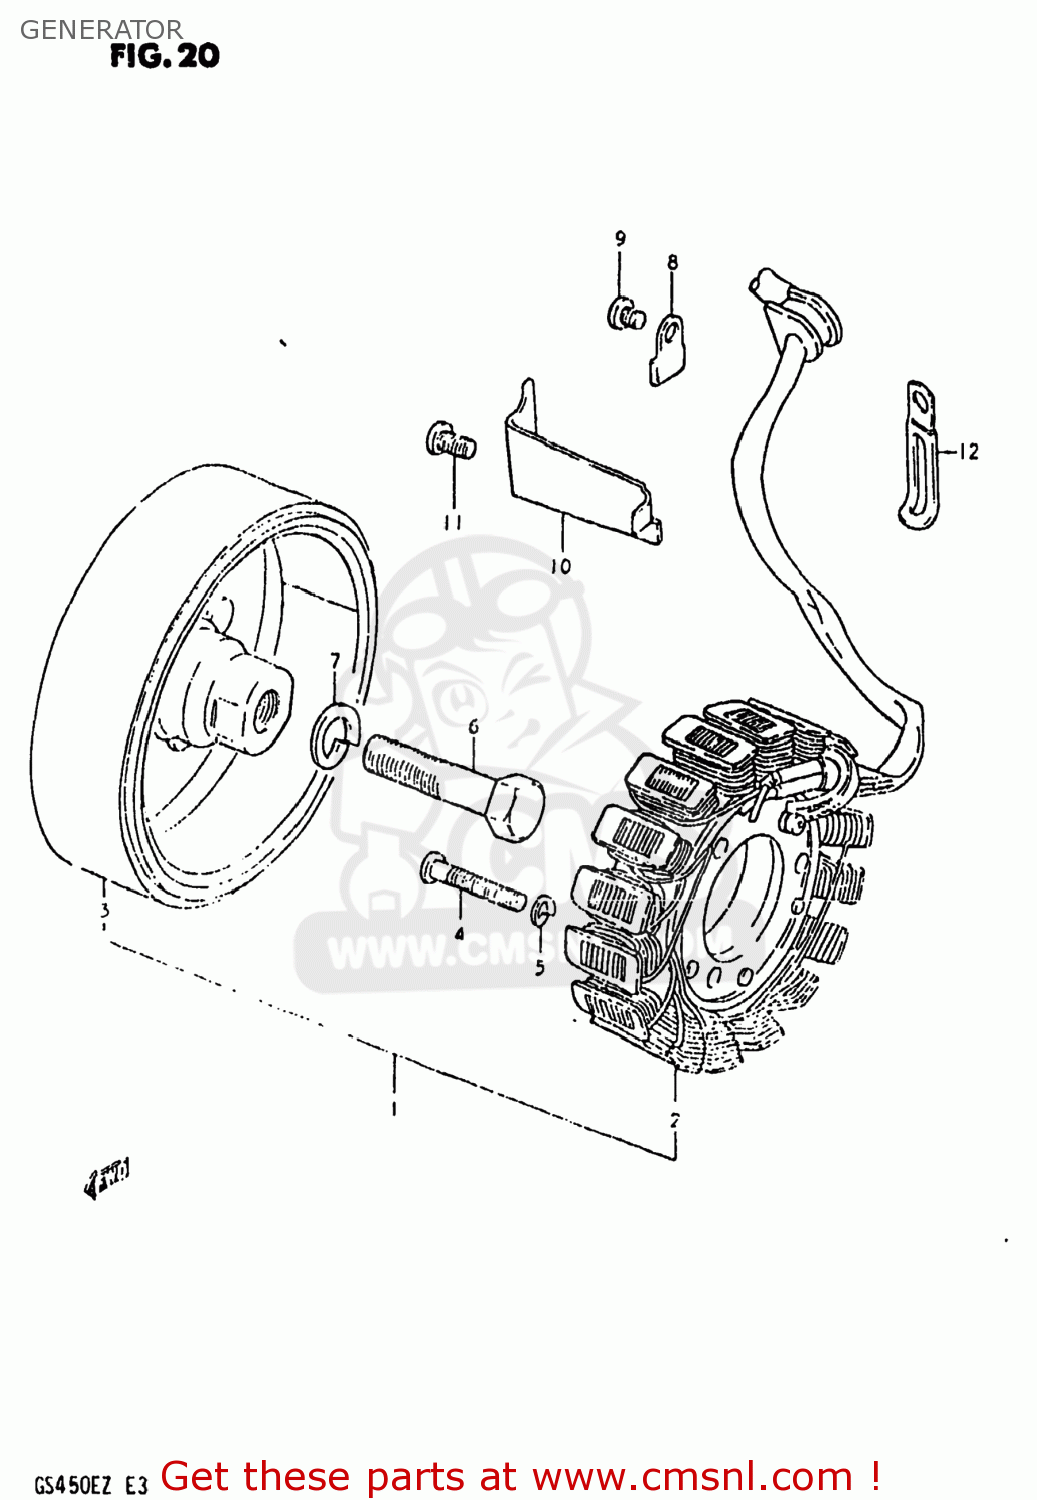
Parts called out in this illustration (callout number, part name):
1	GENERATOR ASSEMBLY
2	STATOR ASSEMBLY
3	ROTOR ASSEMBLY
4	SCREW
5	LOCK WASHER
6	BOLT 12X45
7	WASHER,LOCK 12
8	CLAMP,GENERATOR LEAD WIRE
9	SCREW
10	CLAMP,GENERATOR LEAD WIRE
11	SCREW
12	CLAMP L:35
